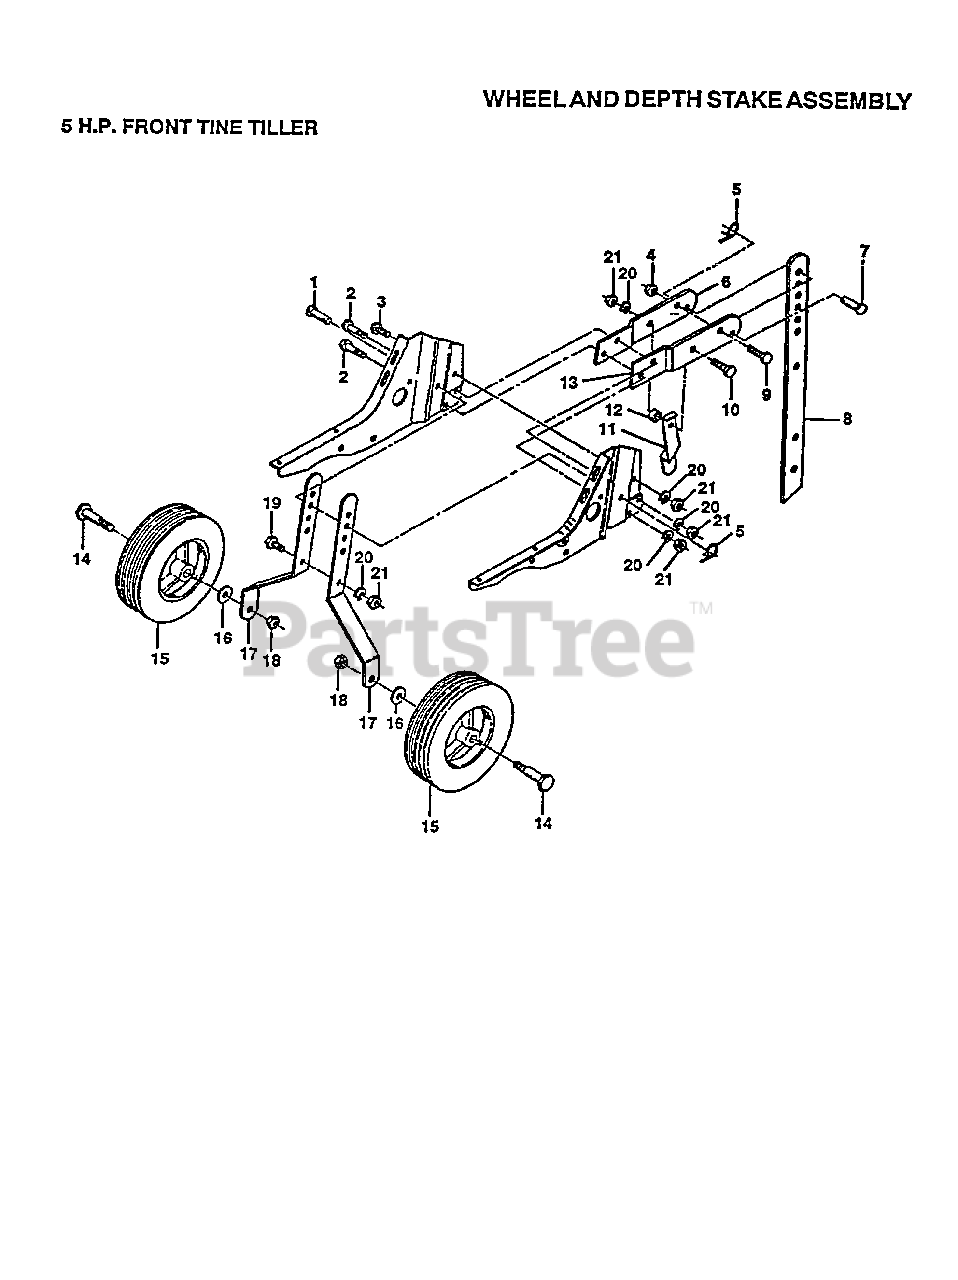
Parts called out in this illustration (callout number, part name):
1	DRILLED RIVET RT
3	BOLT
4	GRIPCO NUT
5	SPRING.RETAINER
9	BOLT.3/8-24X1-1/2
10	BOLT.HEX.5/16-1.5
11	STAKE SPRING TI
12	WASHER
14	BOLT SHOULDER
16	WASHER
20	LOCKWASHER
21	NUT.HEX.5/16-18
